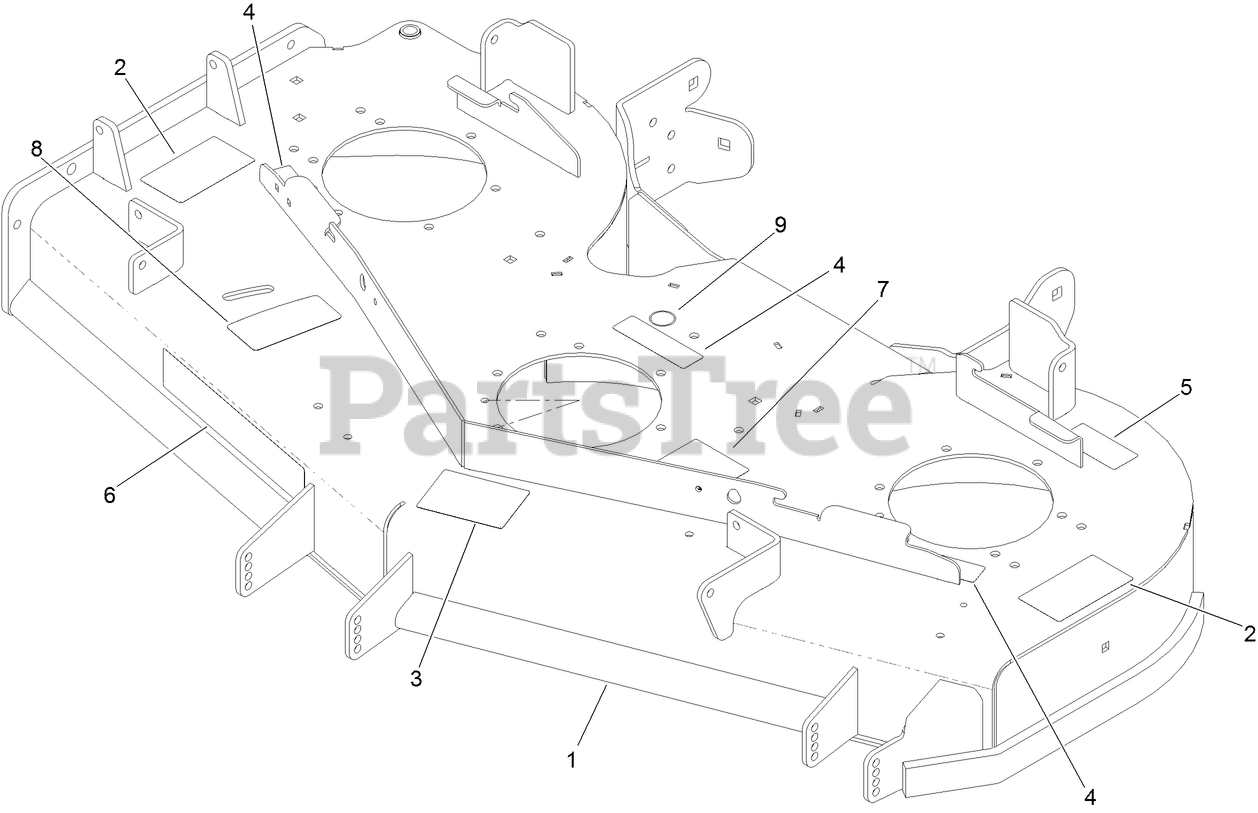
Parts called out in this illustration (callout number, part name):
1	DECK ASM
2	DECAL-DANGER
3	DECAL-SCALP, ANTI
4	DECAL-COVER, MISSING
5	DECAL-BOLT TORQUE
7	DECAL-ROUTING, DECK BELT
8	DECAL-ADJUSTMENT, BAFFLE
9	DECAL-GREASE
